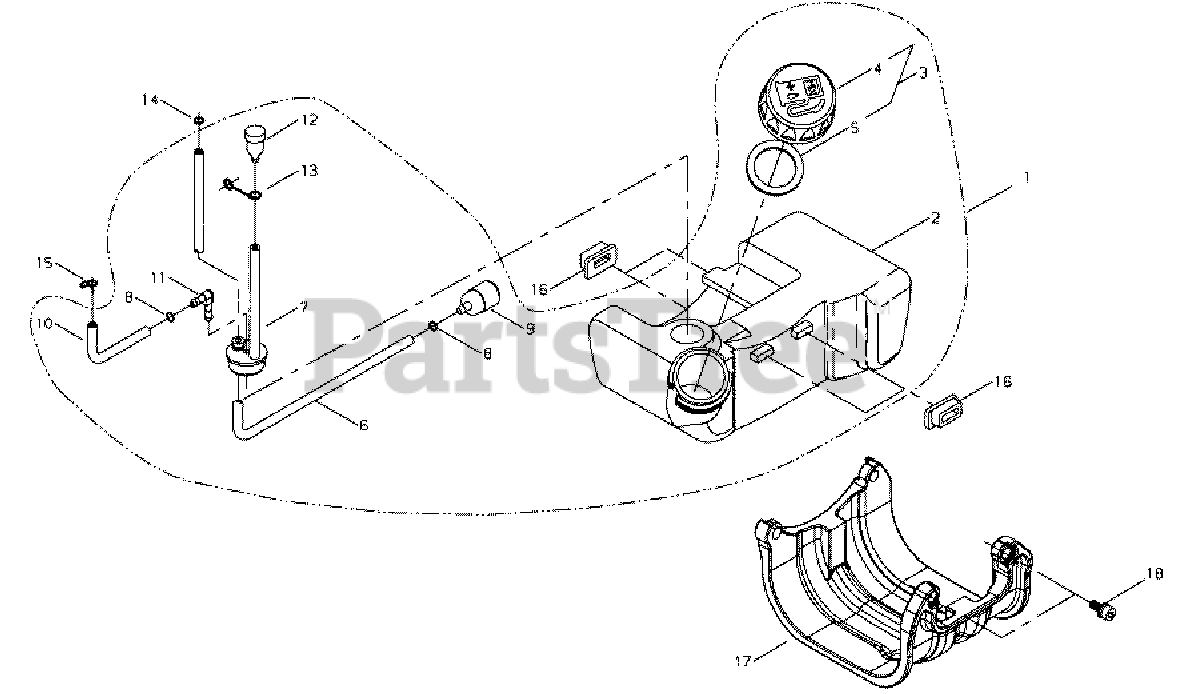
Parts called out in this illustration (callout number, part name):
1	FUEL TANK ASSY
2	TANK, FUEL
3	CAP ASSY, FUEL
4	CAP, FUEL
5	GASKET, FUEL CAP
6	PIPE, FUEL
7	GROMMET, FUEL W/VENT PIPE
8	CLIP Ø6
9	FILTER, FUEL 125-528
10	PIPE, FUEL RETURN
11	CONNECTOR, PIPE
12	VENT ASSY
13	CLIP, VENT ASSY
14	CLIP Ø6
15	CLIP, SPRING Ø5.2
16	CUSHION, FUEL TANK
17	GUARD, PLASTIC FUEL TANK
18	BOLT M5×18
